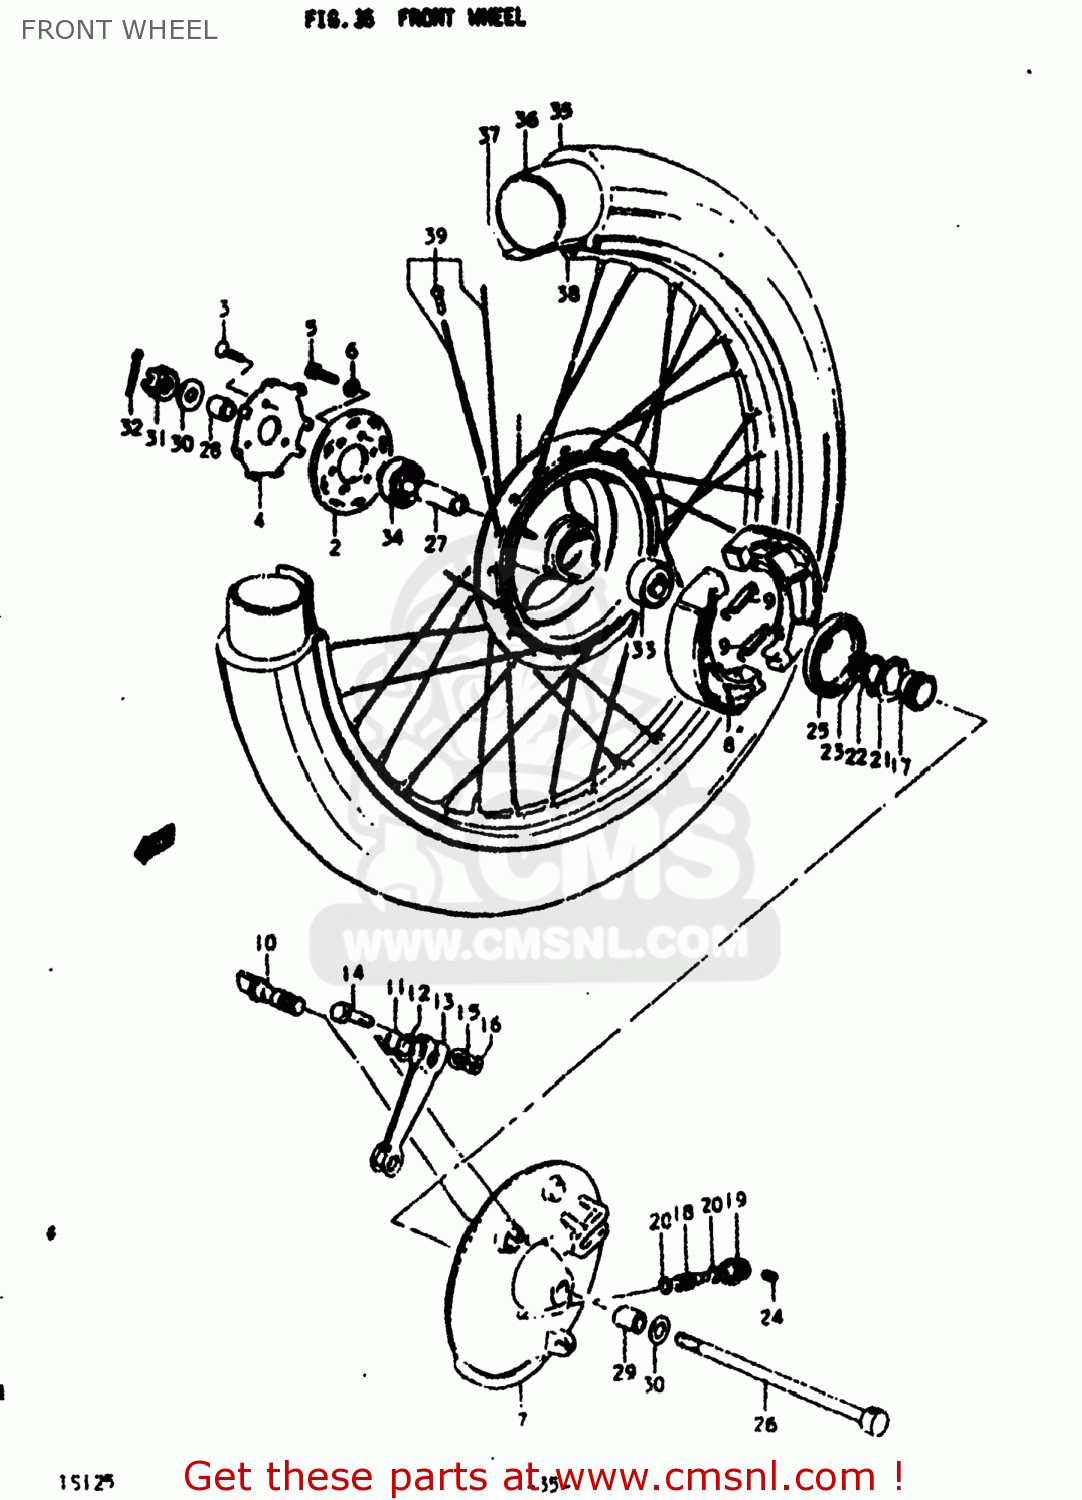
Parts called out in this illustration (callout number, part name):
1	HUB,FR WHEEL
2	FLANGE,FR HUB,R
3	SCREW
4	RETAINER,FR HUB BEARING,R
5	BOLT, UPPER
6	LOCK WASHER
7	PANEL,FRONT HUB
8	SHOE,BRAKE
9	SPRING(L:34)
10	CAM,FRONT BRAKE
11	O-RING (D:2.4 ID:13.8)
12	WASHER (14.5X22X1.6)
13	LEVER,FR BRAKE CAM
14	BOLT(6X33)
15	WASHER
16	NUT
17	GEAR,SPEEDOMETER
18	PINION,SPEEDOMETER
19	BUSH,METER GEAR OUTER
20	WASHER (5.1X9X0.4)
21	DRIVER,SPEEDOMETER GEAR
22	WASHER(18.5X24X1)
23	CIRCLIP
24	SCREW
25	OIL SEAL (43X58X7)
26	AXLE,REAR
27	SPACER (12.6X19X52)
28	SPACER(17X24X4.5)
29	SPACER(12X20X34.5)
30	WASHER
31	NUT 12MM
32	COTTER PIN
33	BEARING
34	BEARING, RH
35	TIRE,FRONT
36	TUBE
37	PROTECTOR,WHEEL,INNER
38	RIM,FR WHEEL(1.60X21)
39	SPOKE SET,FRONT
